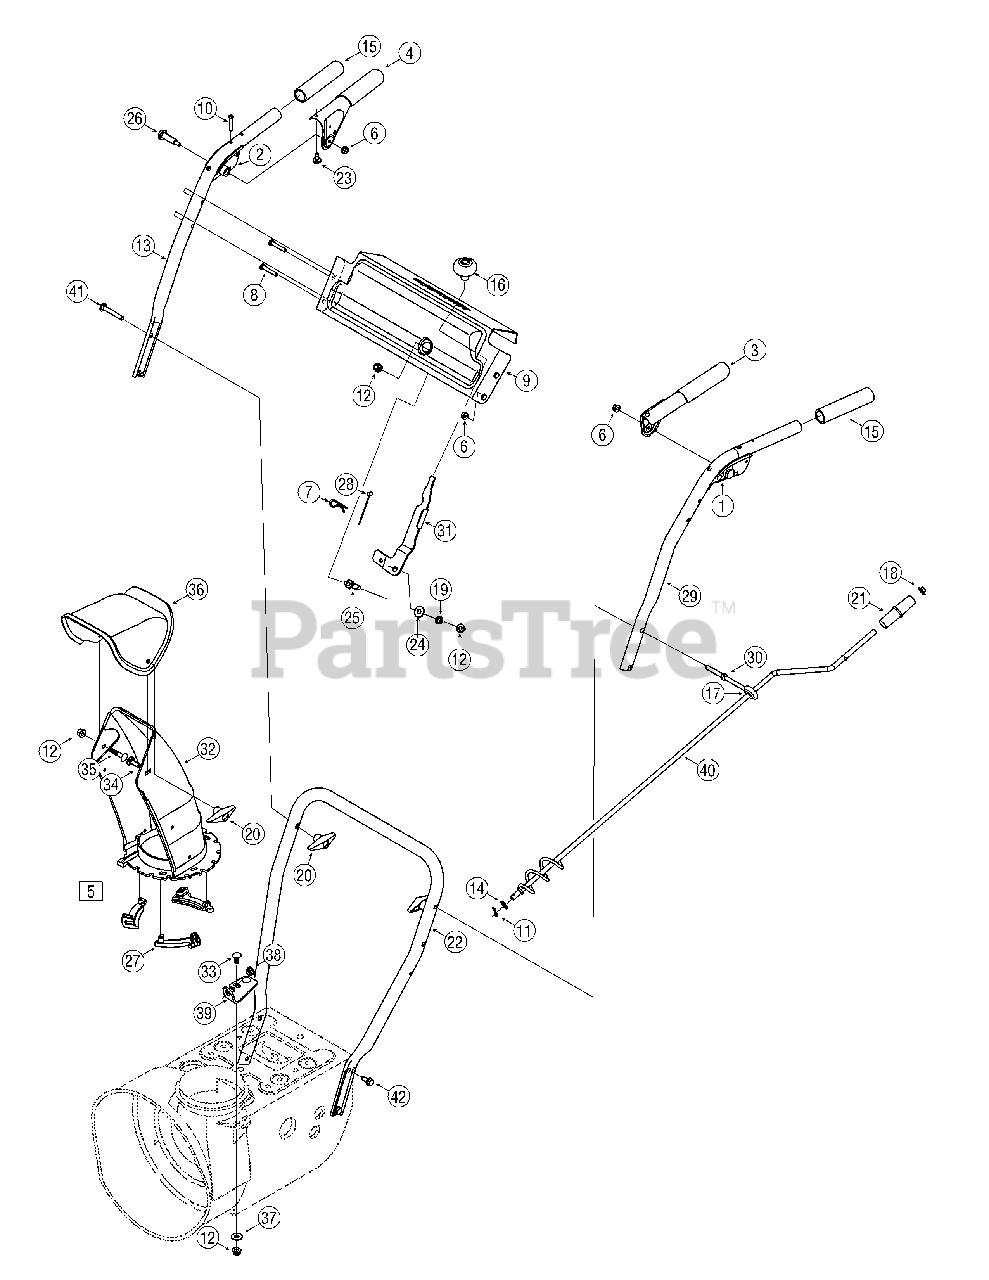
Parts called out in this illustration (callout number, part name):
1	Handle Assembly, Clutch Lock, LH
2	Handle Assembly, Clutch Lock, RH
3	Handle Ass’y, Engage, LH
4	Handle Ass’y, Engage, RH
5	Chute, Lower (Incl. Ref. # 27, Qty. 3)
6	Nut, Flange Lock, 1/4-20
7	Click Pin
8	Screw, 1/4-20 x 1.50
9	Panel, Handle, (no cutout)
10	Screw, Machine, #10-24, 1.375
11	Pin, Cotter, .072 x 1.13
12	Nut, Flange Lock, 5/16-18, Nylon
13	Handle, Upper, RH
14	Washer, Flat, .375 x .738 x .063
15	Grip, 1.0 ID x 5.0
16	Knob, Shift, Black
17	Grommet, .44 ID x .94 OD x .50
18	Cap, Push, 3/8 Rod
19	Spring, .39 x .60 x .88
20	Knob, 5/16-18, Black
21	Crank Knob, 1.0 Dia. x 3.2, Black
22	Handle, Lower
23	Bumper, Rubber, .62 OD x .22
24	Washer, Flat, .385 x .870 x .092
25	Bolt, Shoulder, 5/16-18 x 0.905
26	Screw, Shoulder, .43 x 1.3, 1/4-20
27	Chute, Flange Keeper
28	Cable, Speed Selector
29	Handle, Upper, LH
30	Eye Bolt, Chute Crank
31	Shift Lever
32	Chute, Lower, 5.0 Dia.
33	Bolt, Carriage, 5/16-18, 1.0
34	Bolt, Carriage, 5/16-18, 1.0
35	Bolt, Carriage, 5/16-18, .750
36	Chute, Upper, w/ Label
37	Washer, .349 x .879 x .063
38	Bushing, Plastic, .380
39	Bracket, Chute Crank
40	Crank Assembly, Chute
41	Screw, Carriage, 5/16-18, 2.25
42	Screw, 5/16-18, 2.25, Gr5
